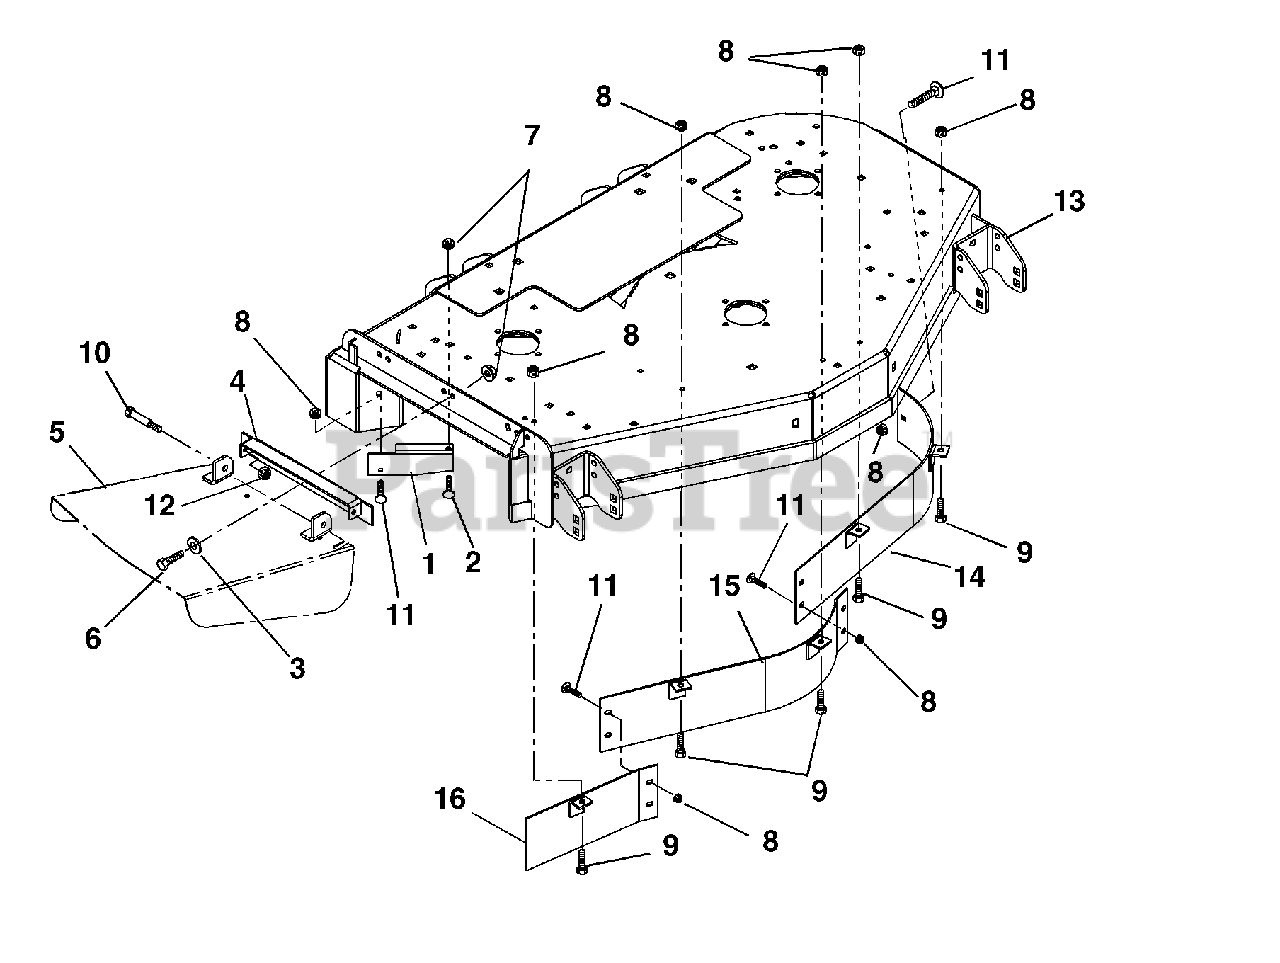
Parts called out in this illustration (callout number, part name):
1	DEFLECTOR - 52"/34"
2	@BLT-RDHDSQNK .38-16X1.00 G5YZ
3	@WSHR-FL-STL.38X.875X.083 YWZC
4	WMT, DISCH CHUTE BRKT - ORANGE
5	DISCH CHUTE - ORANGE
6	@BLT-HEX .38-16X1.00 GR5 YWZC
7	@NUT-LK-TOP-FLG .38-16 YWZC
8	@NUT-LK-TOP-FLG .31-18 YWZC
9	@BLT-HEX .31-18X.75 GR5 YWZC
10	BLT-SHLDR .38-16X.38 SKH
11	@BLT-RDHDSQNK .31-18X.75 G5YZ
12	@NUT-LK-CTR .38-16 YWZC
13	WMT, 52" MOWER DECK - ORANGE
14	BAFFLE - LEFT FRONT - 52"
15	BAFFLE - CENTER FRONT - 52"
16	BAFFLE - RIGHT FRONT - 52"
